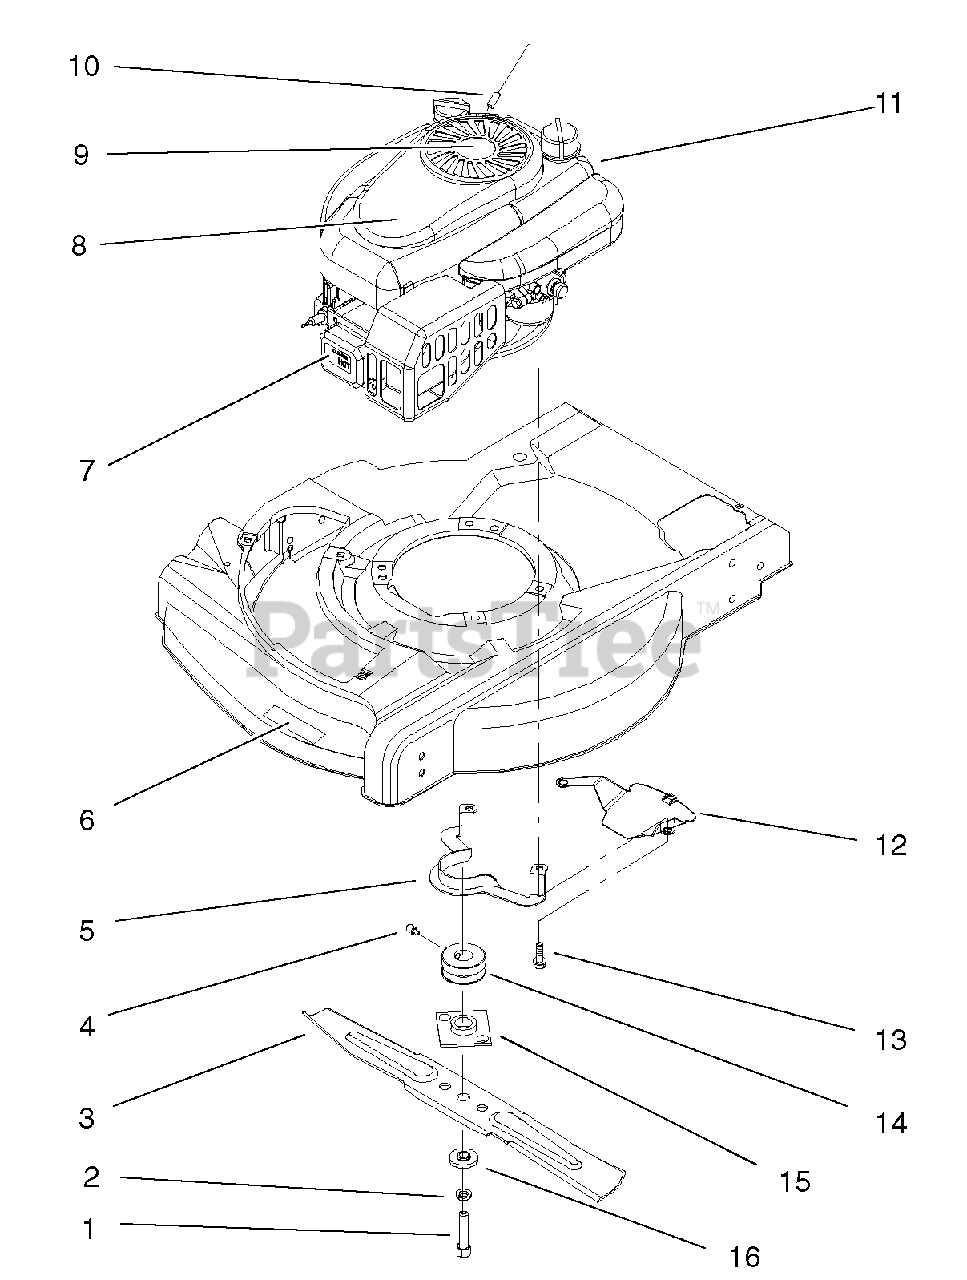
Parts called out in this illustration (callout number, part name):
1	Bolt-Blade
2	Washer-Lock
4	Screw-Set,Cone Point
5	Guide-Belt
6	Decal-Deck
7	Decal-Surface, Hot
8	Applique
9	Decal-Recoil
10	Stop-Rope
11	Engine-Centura Ohv,Zs
12	Shield-Grass
13	Screw-Taptite
15	Plate & Collar ASM
16	Spacer-Blade
